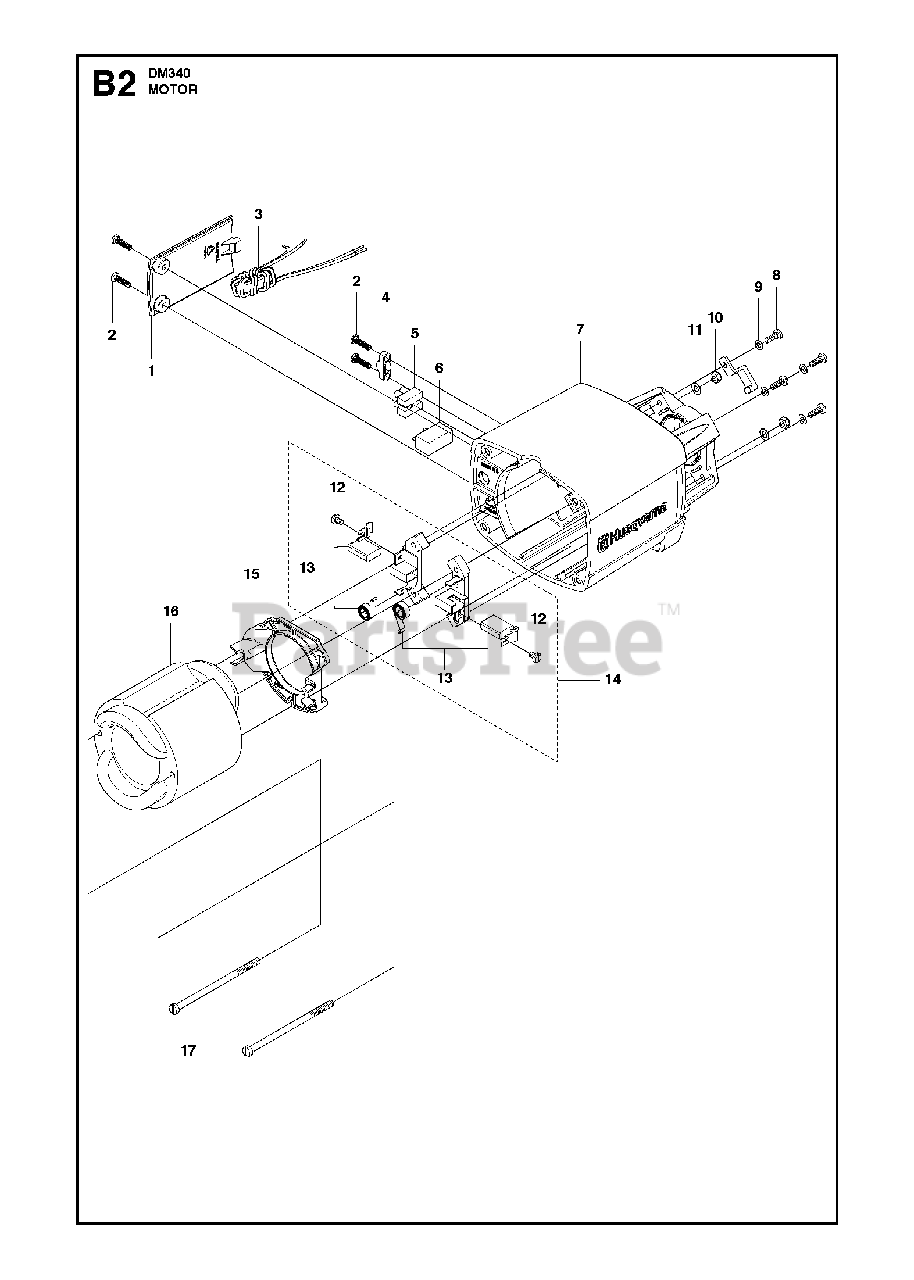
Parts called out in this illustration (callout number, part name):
2	SCREW CCRPANT120V, US
4	CLIP120V, US
5	TERMINAL BLOCK230V, valid until 20154700001
5	TERMINAL BLOCK110V, valid until 20154700001
5	TERMINAL BLOCKValid from 20154700001
9	SPRING WASHER
11	SPRING WASHER
13	BRUSH KITKit includes 2 pcs
14	BRUSH HOLDER
